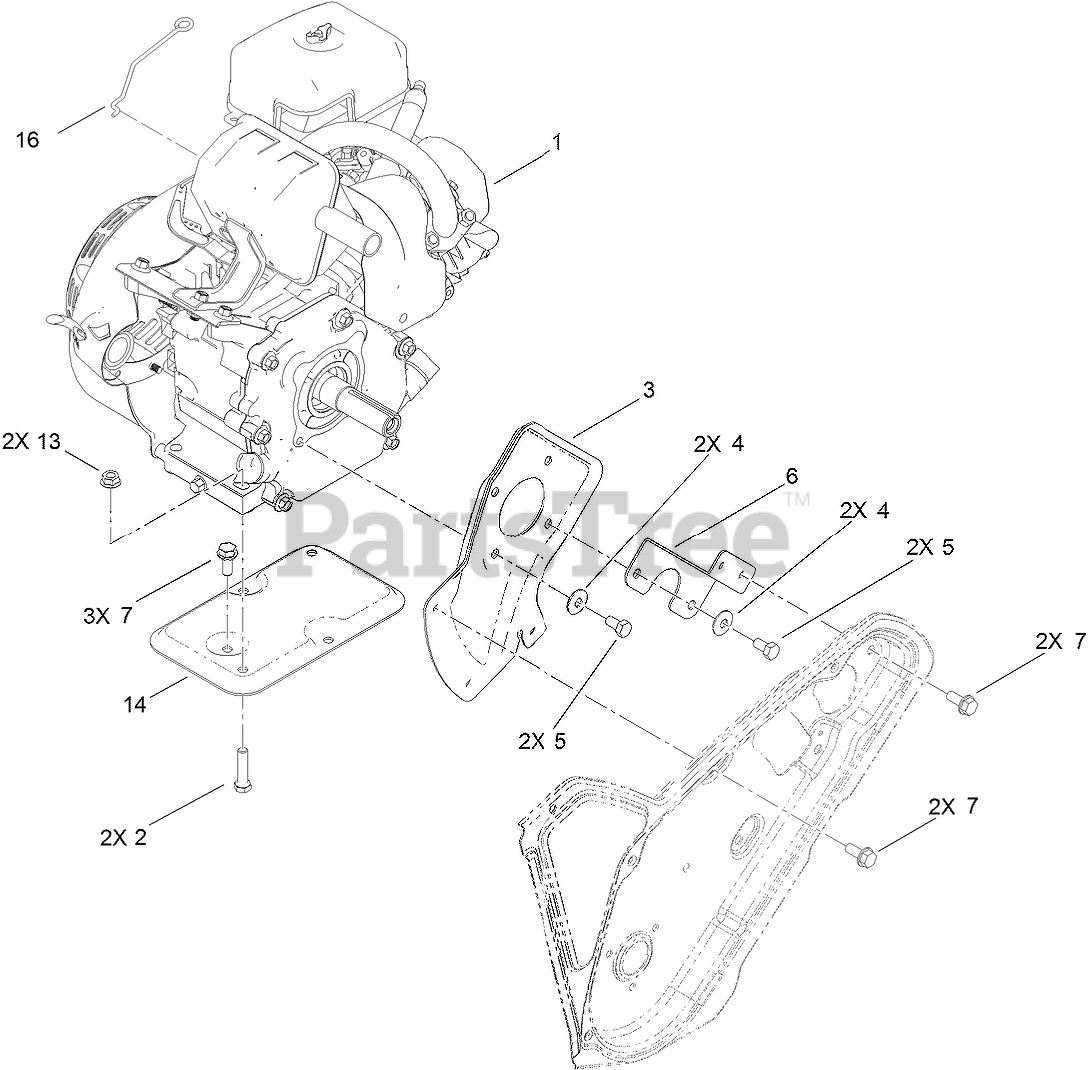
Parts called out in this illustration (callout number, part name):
1	ENGINE-LC168FS-1
2	SCREW-HH
3	PLATE-ENGINE, PTO
4	WASHER-BELLEVILLE
5	SCREW-HH
6	SUPPORT-ENGINE, SIDE
7	SCREW-HWHTF
13	NUT-HF
14	SUPPORT-ENGINE
16	LINK-KNOB, CHOKE
